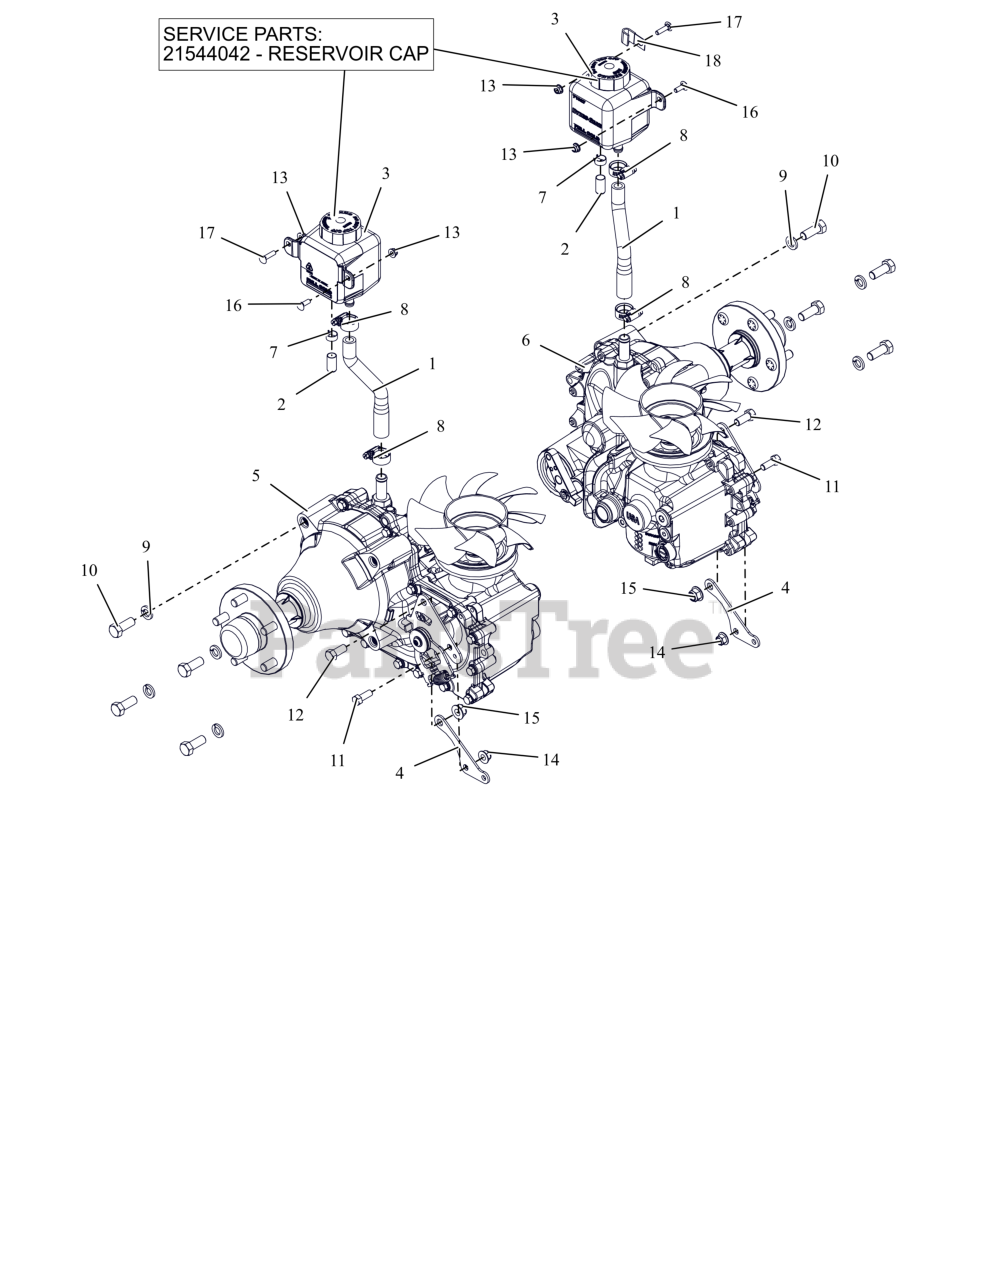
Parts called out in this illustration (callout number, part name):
1	HOSE,PT200/400 TRANS OVERFLOW
2	CAP, .50 BARBED FITTING
3	TANK, HYDRO OVERFLOW 700 ML
3	CAP, HYDRO RESERVOIR REPLAC.
4	DRV CNTRL LINKAGE MTG BRKT-BLK
5	TRANSAXLE, RH HG ZT-5400
6	TRANSAXLE, LH HG ZT-5400
7	CLAMP, .62 SPRING
8	CLAMP,.88 DIA. HOSE
9	WSHR,LK-REG .500X.125 ZCC
10	BLT,HEX .50-13X1.25 G5 ZCC
11	BLT,HEX .38-16X1.00 G5 ZCC
12	BLT, HEX 0.4375-14X1 GR5 ZCC
13	NUT,NYL-FLG .25-20 GF ZCC
14	NUT,NYL-FLG .38-16 GF ZCC
15	NUT,NYL-FLG .44-14 GF ZCC
16	BLT, RHSN .25-20X.750 G5 ZCC
17	BLT, RHSN .25-20X1.00 G5 ZCC
